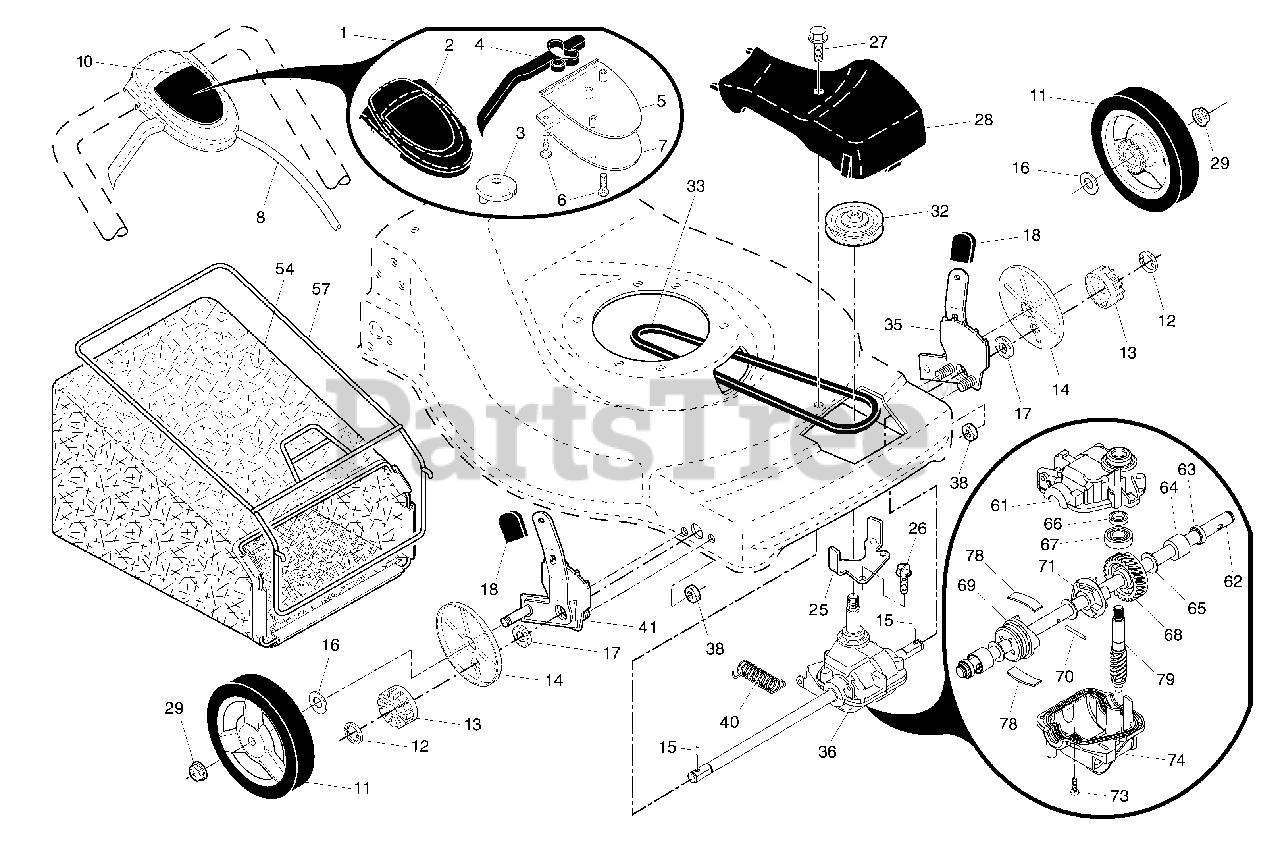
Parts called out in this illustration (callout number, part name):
1	Drive Control Assembly
2	Cover, Drive Control, Top
3	Pulley
4	Lever, Drive Control
5	Cover, Drive Control, Bottom
6	Screw, Torx Head #8 x 5/8
7	Mounting Bracket, Drive Control
8	Cable, Drive Control
10	Decal, Drive Control
11	Wheel & Tire Assembly
13	Gear, Pinion
14	Dust Cover
15	Drive Pawl
16	Washer, Flat 3/8
17	Bearing, Wheel Adjuster
18	Selector Knob
25	Belt Keeper
26	Screw, Hi-Lo Thread #12 x 5/8
27	Pan Head Tapping Screw #10-24 x 2-3/4
28	Drive Cover
29	Locknut, Hex
32	Drive Pulley
35	Kit, Wheel Adjuster, LH
36	Gear Case Assembly, Complete
38	Locknut, Hex 1/4-20
41	Kit, Wheel Adjuster, RH
54	Grassbag Assembly
57	Frame, Grassbag
61	Case, Upper
62	Shaft, Output
63	Seal, Output Shaft
66	Seal, Worm Shaft
67	Bearing, Ball
68	Gear, 28 Teeth
69	Fixed Dog Clutch
70	Pin
71	Movable Dog Clutch
73	Screw, Case
74	Case, Lower
78	Spring, Leaf
79	Shaft, Worm
